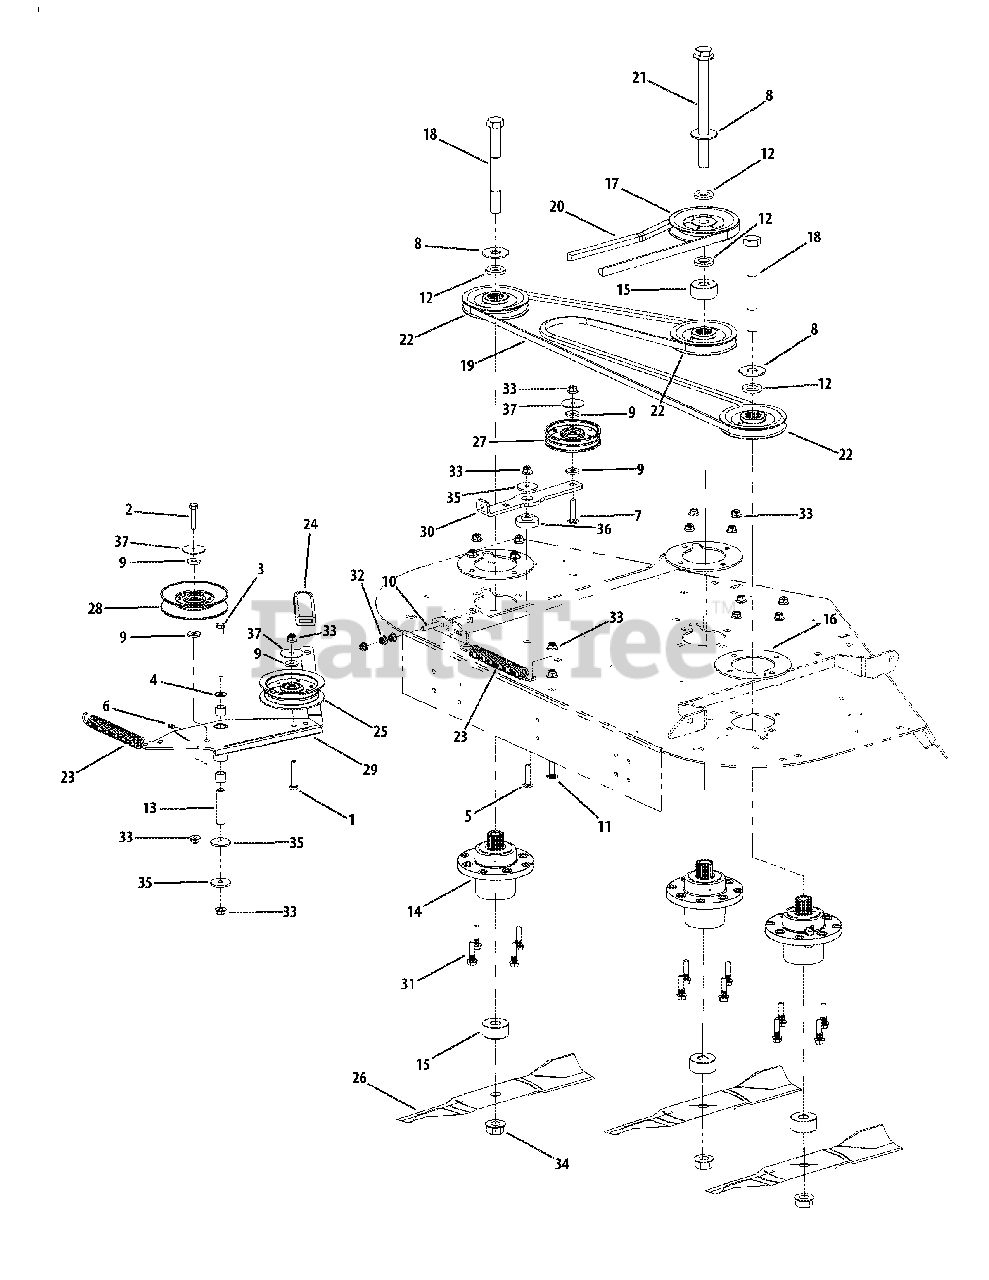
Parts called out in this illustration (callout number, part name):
1	Hex Cap Screw, 3/8-16 x 2.00
2	Hex Cap Screw, 3/8-16 x 1-3/4
3	Hex Cap Screw, 3/8-16, 4.00
4	Washer, 3/8
5	Carriage Bolt, 3/8-16 x 1-1/2
6	Grease Fitting, 1/4-28 x 3/16
7	Hex Carriage Screw, 3/8-16, 2.00
8	Flat Washer, .781 ID 2.00 OD, .105
9	Flat Washer, .406 ID, 1.0 OD, .105
10	Carriage Bolt, 5/16-18 x 1.75
11	Carriage Bolt, 3/8-16 x 1.25
12	Spacer .812 ID x .268 LG
13	Spacer, .39 ID x .625 OD x 2.75
14	Aluminum Spindle Assembly
15	Spacer, .760 ID x 2.000 OD x .900
16	Spindle, Aluminum Cast Support Plt
17	V-Pulley 5.25 OD
18	Hex Cap Screw, 3/4-16, 7.00
19	V-Belt, A Section x 105.3
20	V-Belt, B Section x 87.2
21	Hex Cap Screw, 3/4-16, 9.00
22	V-Pulley, 5.00 OD
23	Extension Spring, .94 OD x 7.57 LG
24	Idler Tension Handle Grip
25	Idler Pulley, 4.06 OD w/Deep Flange
26	Blade, 17.0, Hi-Lift, 0.756 ID
27	Idler Pulley, 4.06 Dia.
28	Idler Pulley, 5.06 Dia.
29	Idler Arm Assembly includes:
29	Bearing
31	Bolt, 3/8-16 x 1.50
32	Nut, Nylon Insert, 5/16-18
33	Nut, Nylon Insert, 3/8-16
34	Nut, 3/4-16, Flangelock
35	Washer, .390 x 1.50 x .134
36	Shoulder Spacer, .854 x .280
37	Washer, .406 x 1.92 x .060
